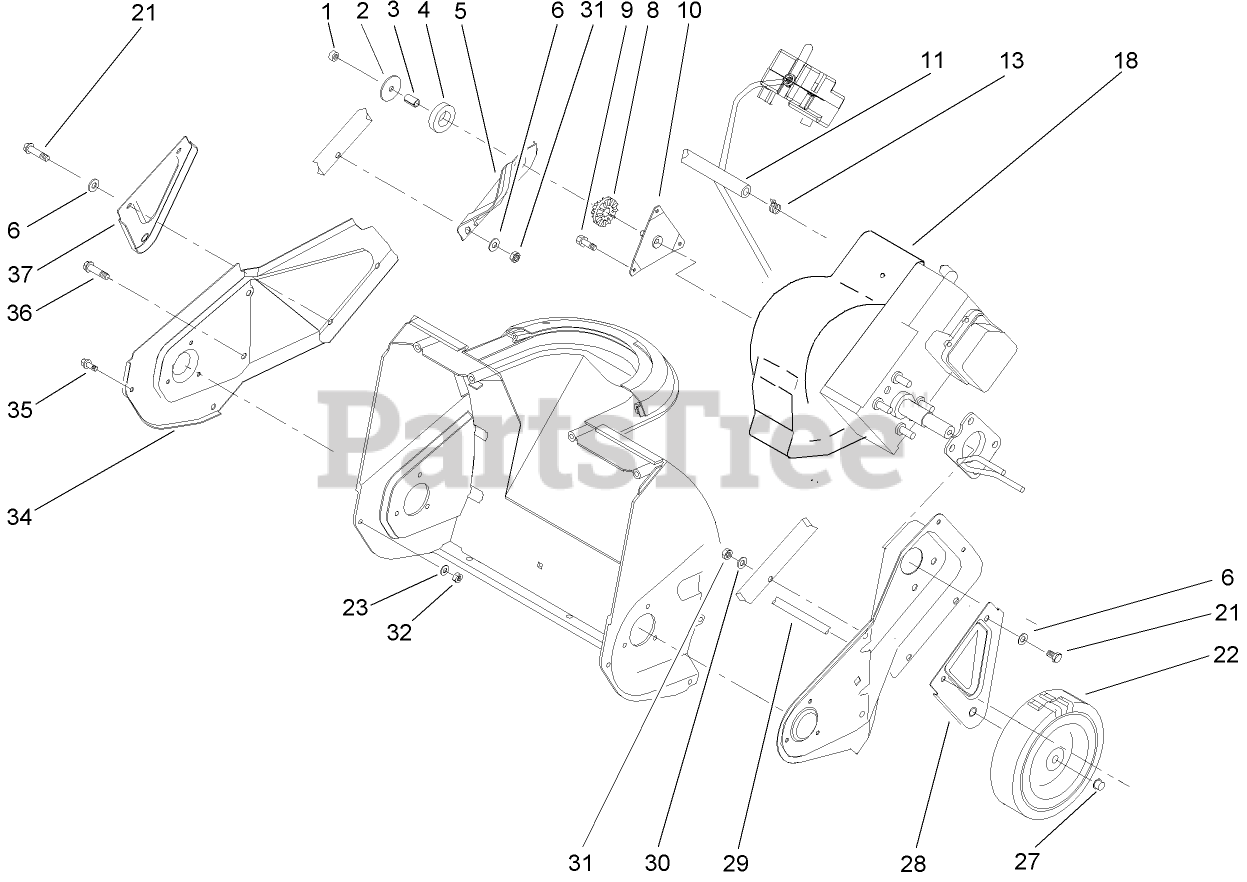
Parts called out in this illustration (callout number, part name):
1	NUT-LOCK, NI
3	SPACER-TUBULAR
4	RING-ISOLATOR
5	BRACKET-SUPPORT, ENGINE
6	WASHER-FLAT
8	BUSHING-ISOLATOR
9	SCREW
10	BRACKET AND STUD ASM
11	LINE-GAS
13	CLAMP-HOSE
18	Loose Parts Package
21	SCREW-HH
22	WHEEL
23	WASHER-FLAT
27	NUT-PUSH
28	BRACKET-WHEEL, LH
29	AXLE SHAFT
30	WASHER
31	NUT-LOCK, NI
32	NUT-LOCK, NI
34	PLATE-SIDE, RH
36	SCREW-PLASTIC
37	BRACKET-WHEEL, RH
